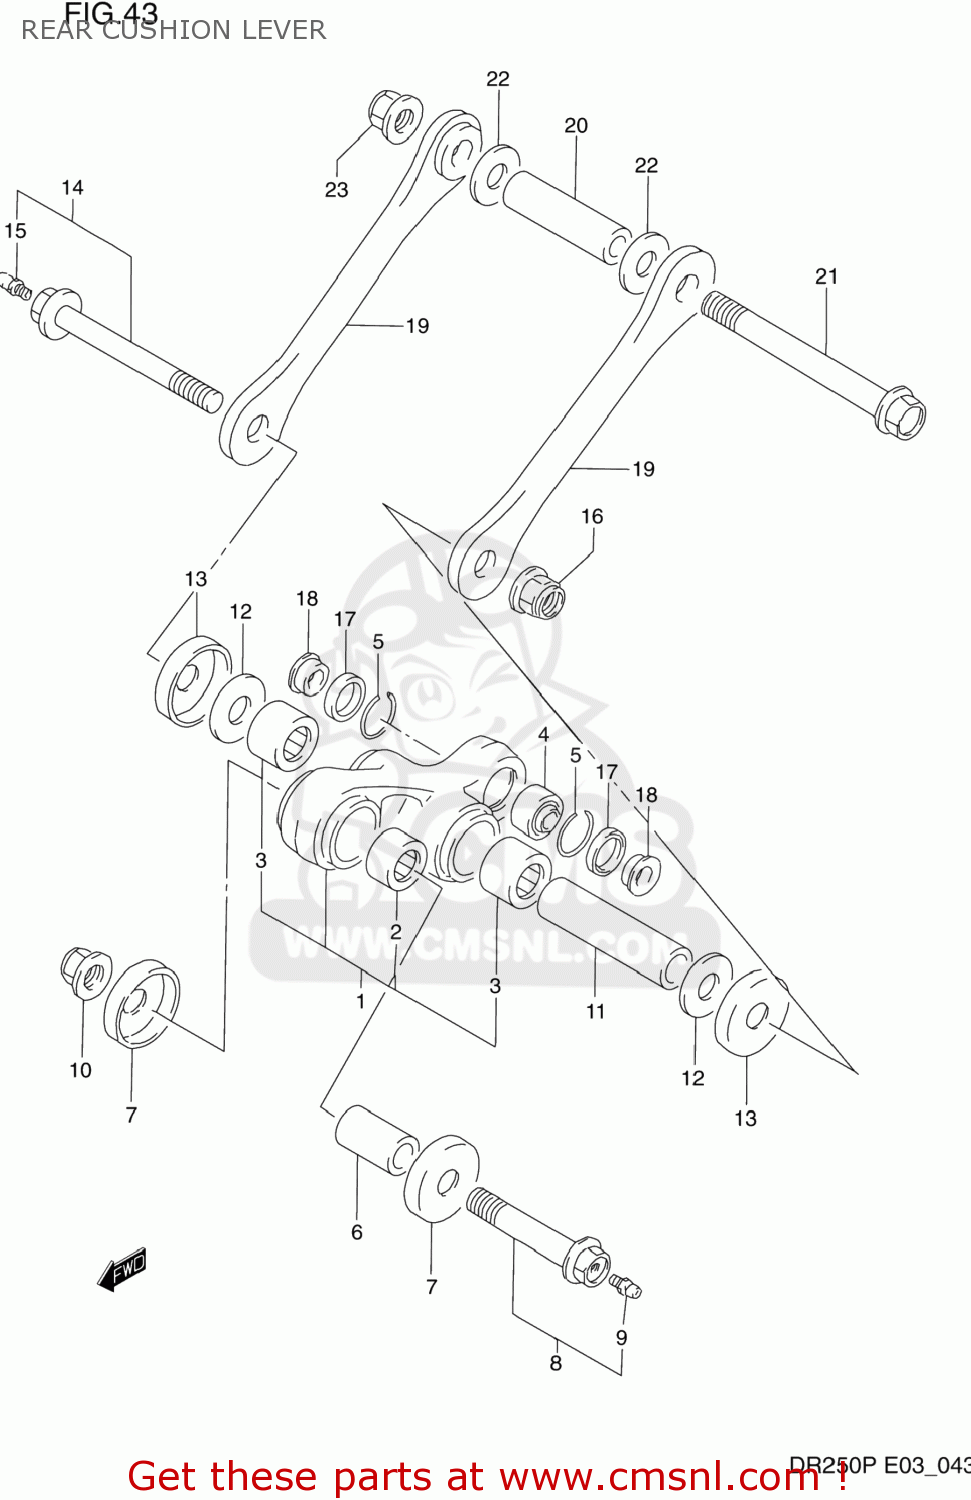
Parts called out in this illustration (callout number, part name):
1	LEVER SET,RR CUSHION
2	BEARING(20X27X32)
3	BEARING(20X27X23.5)
4	BEARING,REAR SHOCK ABSORBER
5	RING
6	SPACER,RR CUSHION LEVER FR
7	SEAL,REAR CUSHION LEVER
8	BOLT,RR CUSHION LEVER FR
9	GREASE NIPPLE
10	NUT 12MM
11	SPACER,RR CUSHION LEVER CTR
12	WASHER
13	SEAL,RR CUSHION LEVER
14	BOLT,RR CUSHION LEVER CTR
15	GREASE NIPPLE
16	NUT
17	SEAL,OIL(17X24X3)
18	COLLAR
19	ROD,RR CUSHION
20	SPACER,RR CUSHION ROD
21	BOLT,RR CUSHION ROD
22	WASHER
23	NUT
